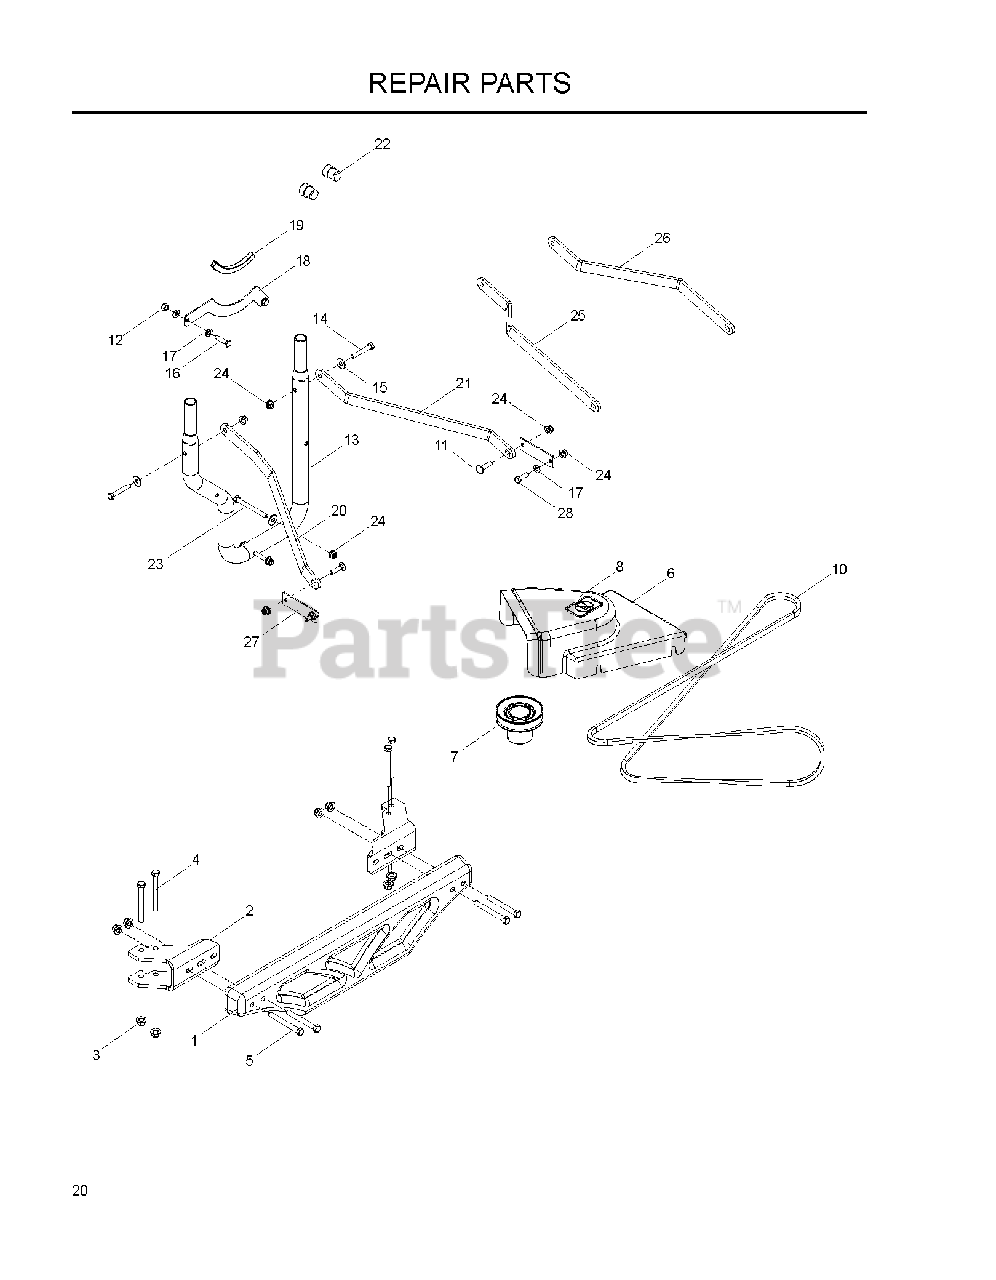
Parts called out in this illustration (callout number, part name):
1	CAST WEIGHT
2	BRACKET WEIGHT BLK
3	NUT 3/8-16 HEX FLG NYLOC ZD
4	HCS 3/8-16 X 3-1/2 GR5 ZD
5	HCS 3/8C X 3
6	SHIELD, BELT, 48"
7	PULLEY, 42/48"
8	DECAL, NO STEP
9	Mount Plate
10	Belt for 48" and 52" Grass Collection System
11	BOLT, CARRIAGE 5/16X1-1/4
12	NUT 5/16 NYLOC
13	MOUNT.TUBE.COLLECTIONS
14	HCS 5/16-18X2
15	WASHER 5/16 FLAT
16	HCS 5/16C X 1 1/4
17	FLAT WASHER 5/16 SAE
18	Collection Chute Support, Black
19	Flex Trim, 1' Black
20	STRAP, SUPPORT, RT PTD
21	STRAP, SUPPORT, LT PTD
22	SPACER PLUG, BAGGER
23	HCS 5/16-18 X 3 1/4
25	STRAP, SUPPORT, RT BLK
26	STRAP, SUPPORT, LT BLK
27	REINFORCEMENT PLATE BLK
28	HCS 5/16C X 1
